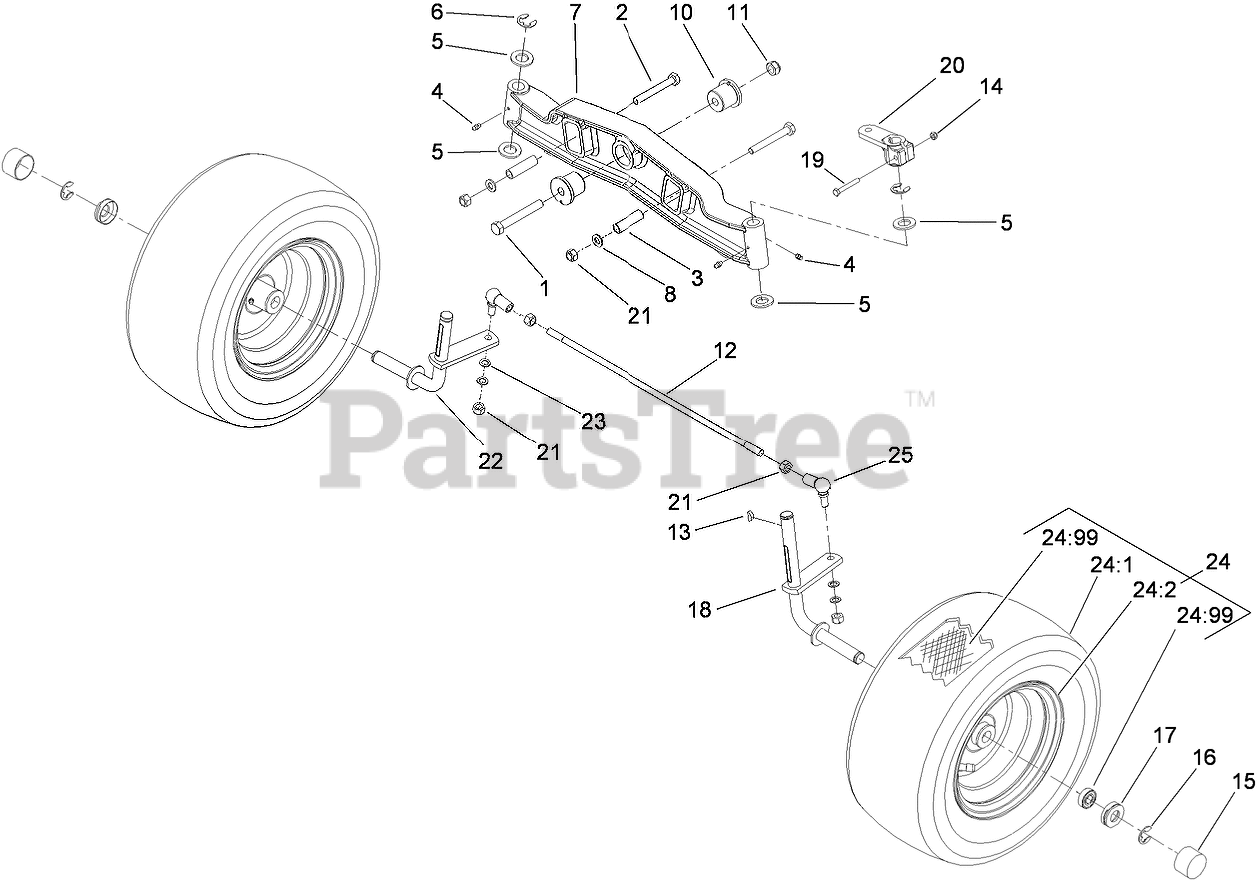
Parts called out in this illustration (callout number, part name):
1	SCREW-HH
2	SCREW-HH
3	SPACER
4	FITTING-GREASE
5	WASHER-FLAT
6	CLIP-SPRING
7	AXLE-FRONT
8	WASHER-FLAT
10	BUSHING-AXLE, FRONT
11	NUT-LOCKING, SELF
12	ROD-TIE, FRONT AXLE
13	KEY-WOODRUFF
14	NUT-LOCK
15	CAP-HUB
16	CLIP-SPRING
17	RETAINER-CAP, HUB
18	SPINDLE-FRONT, LEFT
19	SCREW-HH
20	LEVER-SPINDLE, STEERING
21	NUT-LOCK, NI
22	SPINDLE-FRONT, RIGHT
23	Washer
24	WHEEL ASM
24:2	RIM-FRONT
24:99	TUBE-INNER
24:99	BEARING-WHEEL
25	JOINT-BALL, ANGLE
